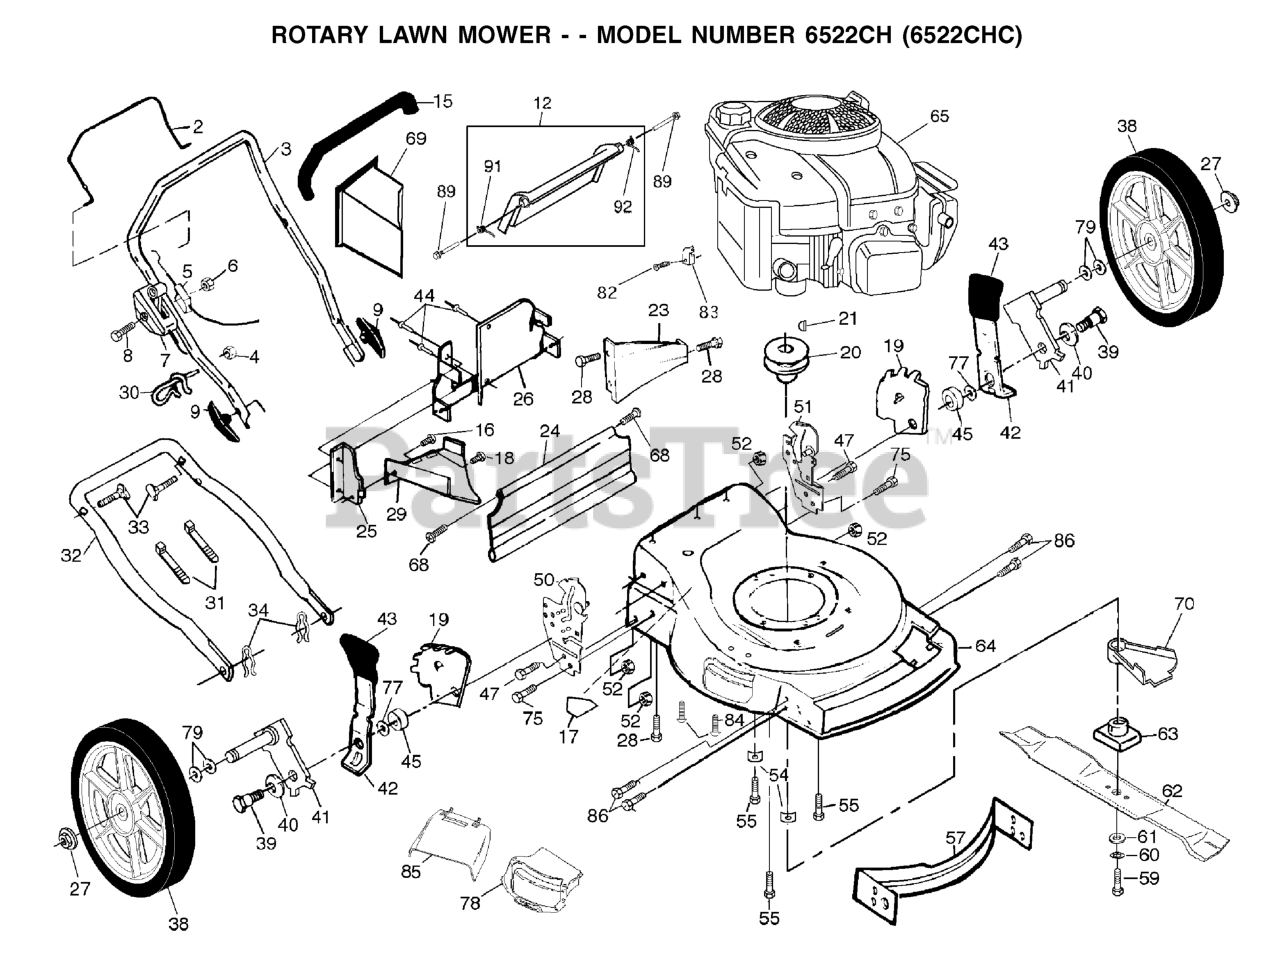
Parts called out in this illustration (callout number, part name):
3	HANDLE, UPPER DLX COMF. (GRIP)
4	NUT
5	CABLE.MZR.51.RT.SP./PU.
6	NUT
7	THROTTLE CONTROL
8	SCREW 1/4-20 X 2.12
9	HANDLE KNOB
12	REAR DOOR KIT
15	GRIP.HANDLE.FOAM
16	SCREW.HXTAP.10-24
17	DECAL HYT
18	SCREW.HXTAP.10-24
19	WHEEL ADJ BRKT
20	ENGINE.PULLEY.FWG
21	HI PRO KEY PM WSL
23	REAR BAFFLE
24	REAR SKIRT
25	SIDE BAFFLE
26	BACK PLATE
27	HEX FLANGE LOCKNT
29	DISCHARGE BAFFLE
30	ROPE, GUIDE
31	TIE GUIDE
32	LOWER HANDLE
33	HANDLE BOLT
34	HAIRPIN COTTER
38	WHEEL.14X2.PR.SP.RAD.GY
39	BOLT
44	RIVET BLIND
45	RP SPACER HT ADJ
47	SELF-TAPPING SCREW 5/16-18X3/4
52	LOCKNUT PM
54	WASHER.ENGINE.BZP
55	BOLT 3/8-16X1-1/8
59	SCREW, HEX HD 3/8-24 X 1-3/8
60	LOCKWASHER
61	WASHER,HARDEN
63	BLADE ADAPTOR
68	HINGE SCREW
69	PLUG.MULCH.22RD
70	DEBRIS SHIELD
77	WASHER.FLAT.1/2
79	WAVE WASHER
82	SCREW.HEX.HEAD.WASHER.10-16
83	WASHER
84	NUT
86	SCREW 1/4X20
89	DOOR BOLT
91	DOOR SPRING RH
92	DOOR SPRING LH
